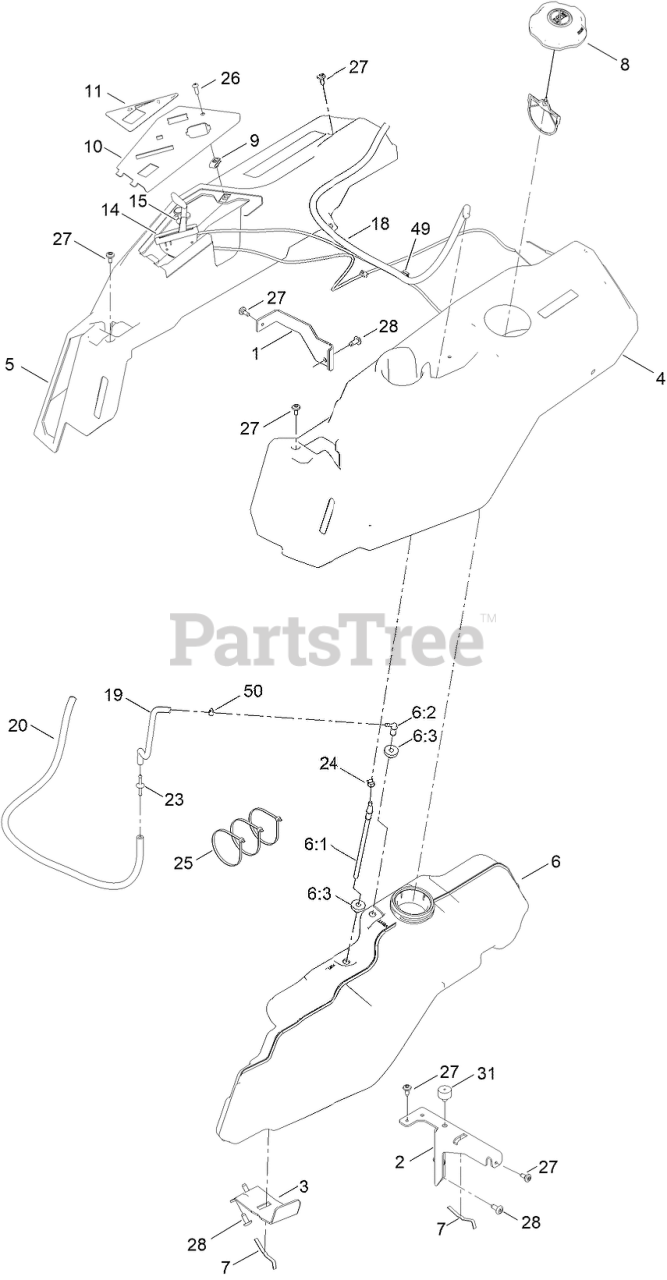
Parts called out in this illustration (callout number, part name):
1	BRACKET-POD
2	SUPPORT-POD, LH
3	SUPPORT-TANK, FUEL
4	POD-LH
5	POD-RH, MYRIDE
6	TANK-FUEL ASM
6:1	CONNECTOR-ELBOW, 90 DEG
6:2	FITTING-ELBOW 90
6:3	BUSHING
7	SPRING
8	CAP-FUEL, RATCHETING
10	PANEL - CONTROL
11	DECAL-PANEL CONTROL
14	CABLE-THROTTLE
15	CABLE-CHOKE
18	HOSE-FUEL
19	HOSE-FUEL
20	HOSE-FUEL
23	ADAPTER ORIFICE
24	CLAMP-HOSE
25	TIE-CABLE
26	SCREW-PRH
27	SCREW-SHOULDER
31	BUMPER-GROMMET
49	CLIP-HARNESS
50	CLAMP-HOSE
